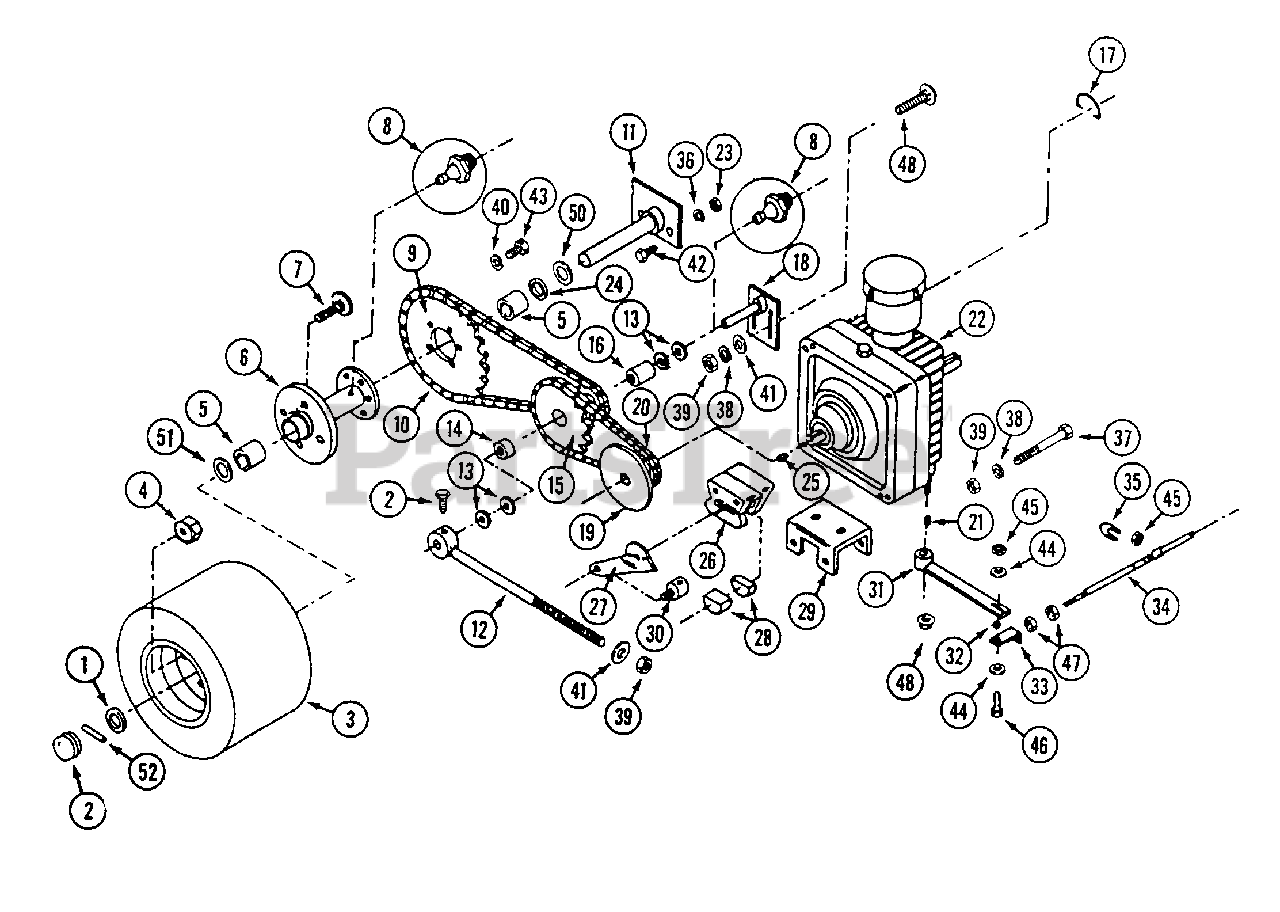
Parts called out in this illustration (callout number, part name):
1	SPACER - hub
3	WHEEL ASSEMBLY - drive
4	NUT - lug 1/2" - 20
5	BEARING - wheel hub
6	HUB - wheel
7	BOLT - lug 1/2" - 20 x 1-1/4"
8	FITTING - grease 1/4" - 28 self tapping
9	SPROCKET - final Drive
10	CHAIN - final drive
11	AXLE - drive wheel
12	COLLAR - support
13	WASHER - 3/4" 10 ga.
14	BEARING - idler sprocket 1/2"
15	SPROCKET - idler
16	BEARING - idler sprocket 3/4"
17	CLIP - transmission dump valve
18	SHAFT - idler sprocket
19	SPROCKET - transmission
20	CHAIN - primary drive
21	KEY - 1/8" x 3/8" Woodruff
22	TRANSMISSION L.H. (CW)
22	TRANSMISSION - R.H. (CCW)
23	NUT - 1/2" - 13
25	KEY - woodruff 1/8" x 112"
26	CALIPER - brake
27	LEVER - caliper L.H.
28	PAD - brake (set)
29	BRACKET - caliper
30	COLLAR - caliper rod
31	ARM - transmission L.H.
31	ARM - transmission R.H.
32	BUSHING - cable end
33	END - steering cable
34	CABLE - steering
35	CLAMP - steering cable
36	LOCKWASHER - 1/2"
37	BOLT - 3/8" - 16 x 3"
38	LOCKWASHER - 3/8"
39	NUT - 3/8" - 16
40	LOCKWASHER - 5/16"
41	WASHER - 3/8"
42	BOLT - 1/2" - 13 x 1-3/4"
43	BOLT - 5/16" 18 x 1"
44	WASHER - 1/4"
45	NUT - 1/4" - 20 lock
46	BOLT - 1/4" - 20 x 1"
47	NUT - #10 - 32 lock
48	BOLT - carriage 3/8" - 16 x 1-1/4"
50	SHIM - .050"
51	SHIM - .010"
52	PIN - roll 1/4" x 1-1/2"
